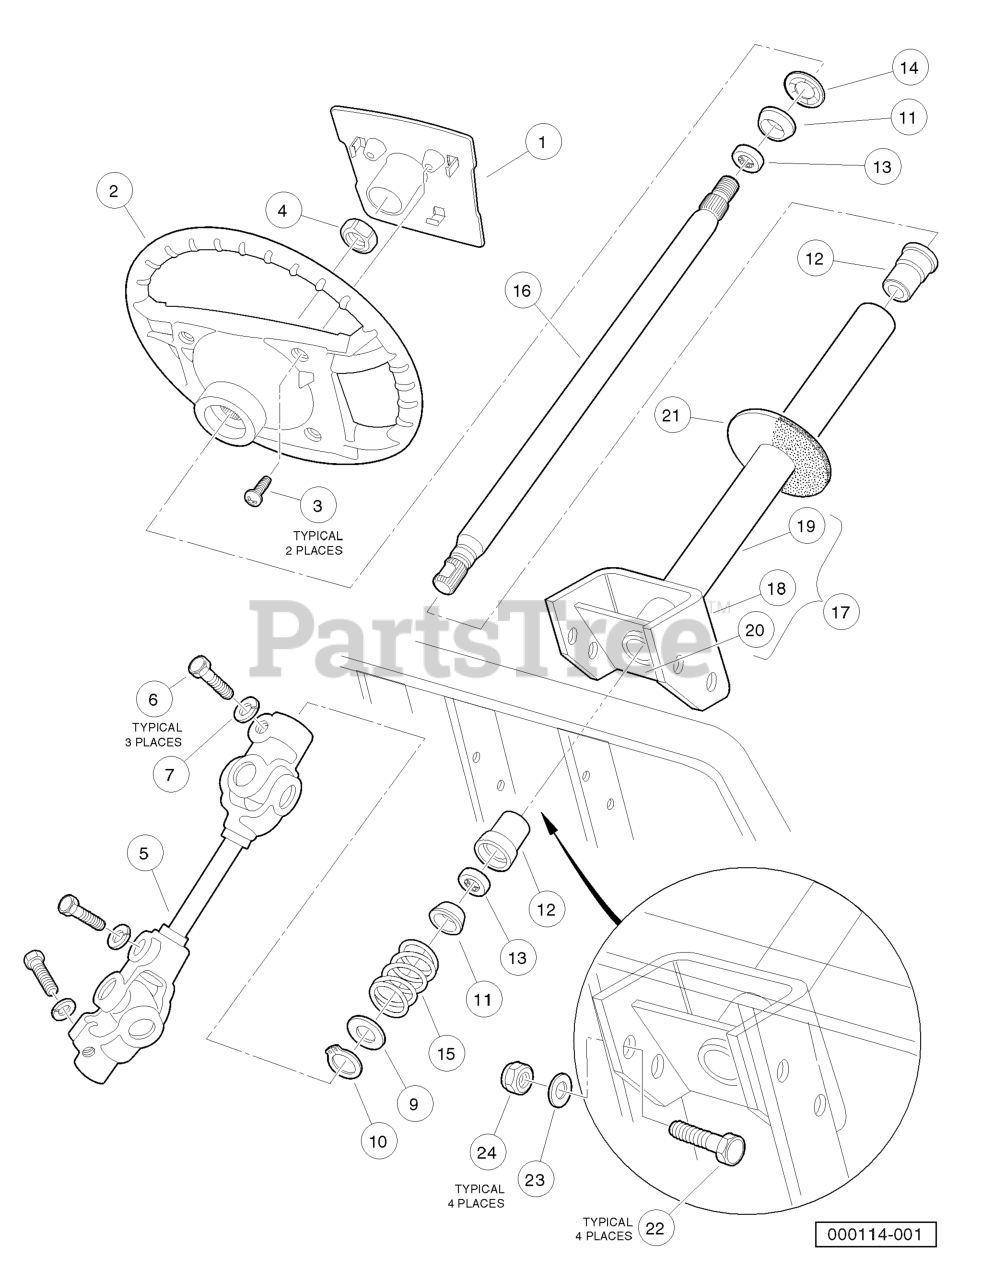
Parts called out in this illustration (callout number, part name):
2	WHEEL ASSY, SPL. HUB STEERING
3	SCREW, #12-14 X .625 TYP AB PN
4	NUT, 5/8-18 NYLON INSERT JAM
5	YOKE ASSEMBLY
6	HEX HEAD BOLT, 8MM X 1.25 - 30
7	LOCKWASHER, 5/16 SPLIT
8	STEERING COLUMN
11	WEDGE MOLDED
12	SEAT, PLASTIC BEARING
13	BEARING ASSY STEERING SHAFT
14	RING, RETAINING
15	SPRING, STEERING SHAFT COMP
16	SHAFT STEERING COLUMN
17	COLUMN WELD ASSY, STEERING
18	Column Mtg Bracket
19	Steering Column
20	Steering Bracket Brace
21	BOOT, STEERING COLUMN ROUND
22	SCREW, CAP, HEX HD 3/8-16X1.00
23	WASHER, 3/8 FLAT
24	LOCKNUT, 3/8-16 HEX
